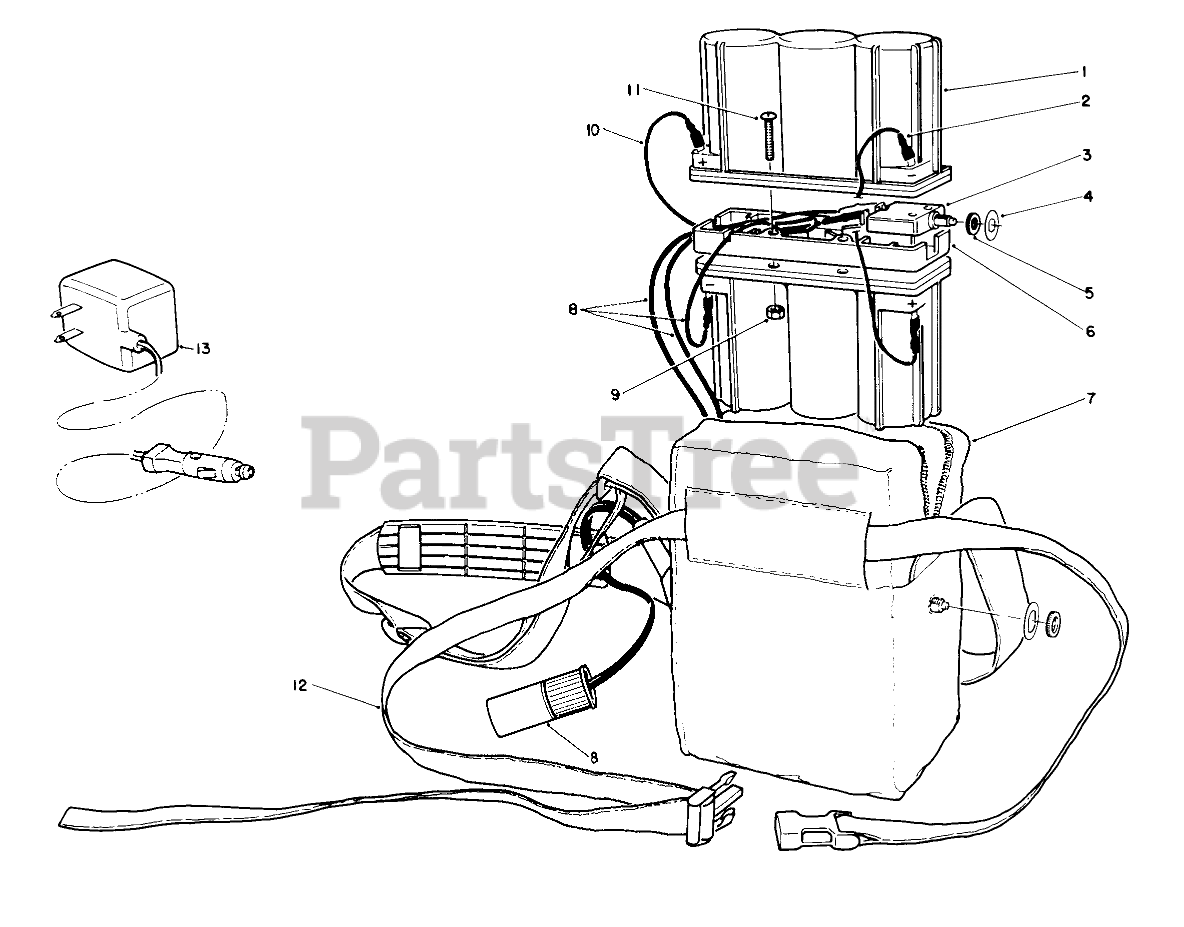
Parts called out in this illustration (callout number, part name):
1	BATTERY, 6 VOLT
2	WIRE ASSEMBLY-BATTERY
3	CKT BREAKER 15 AMP 125V
4	CIRCUIT BREAKER PLATE
5	KNURLED NUT
6	BATTERY SPACER
7	Pack-Soft
8	CORD-BATTERY PACK
9	NUT-HEX
10	WIRE ASSY-CIRCUIT BREAK
11	SCREW-PPH
12	BELT-WAIST
13	Charger 12 Volt
